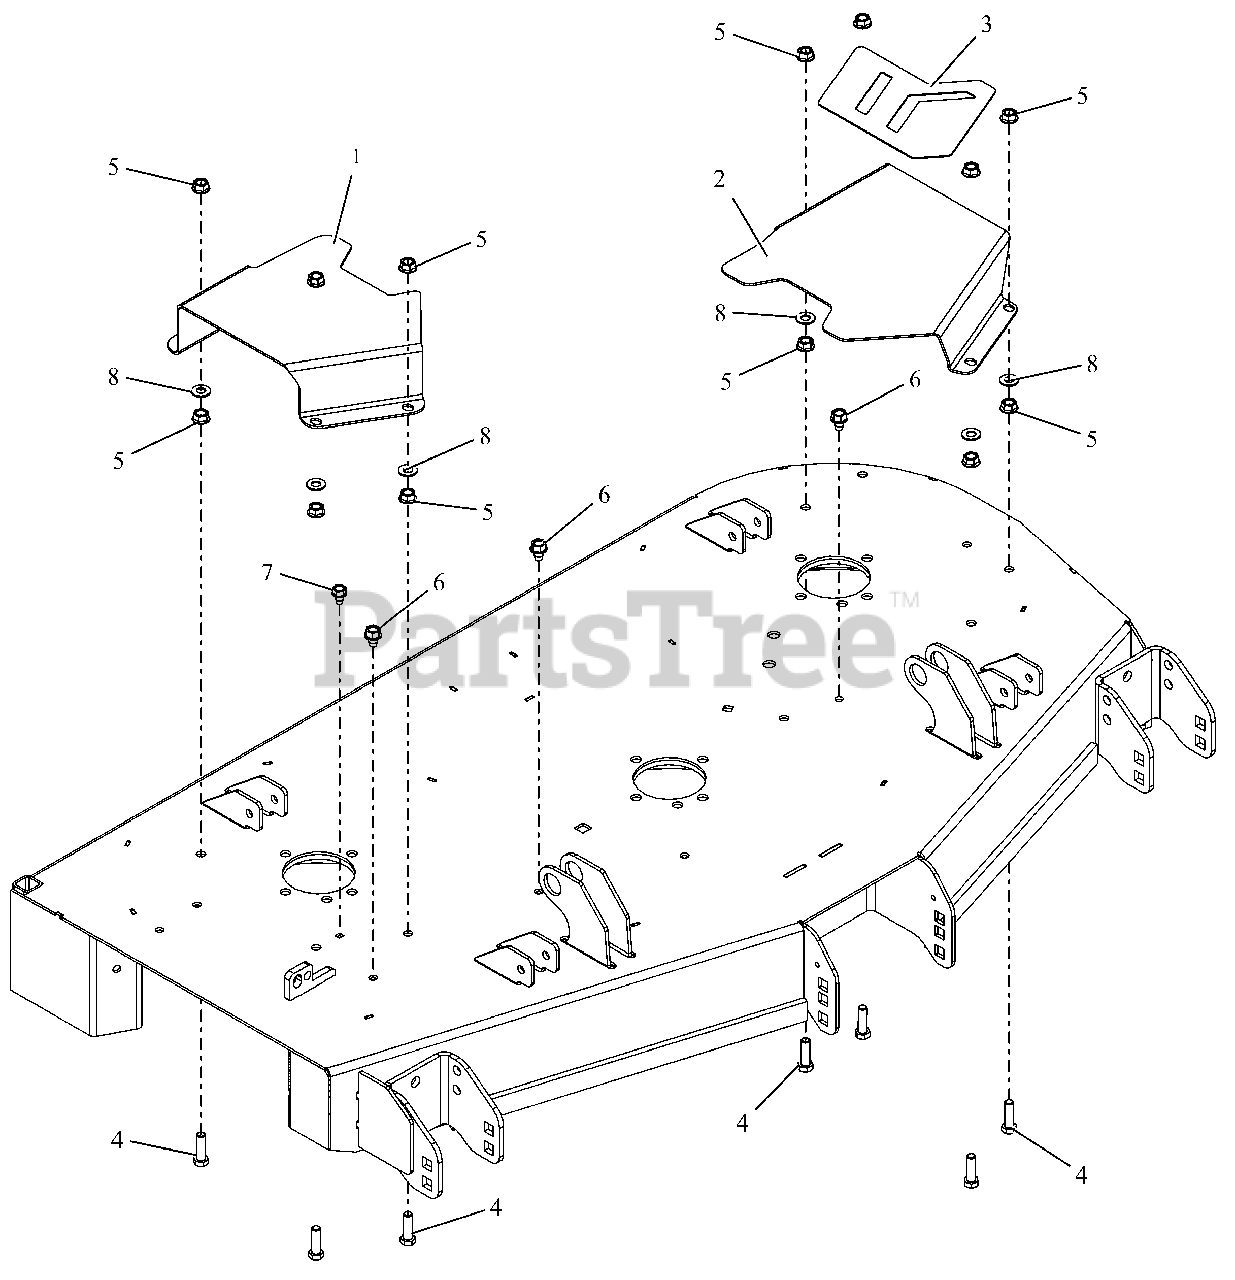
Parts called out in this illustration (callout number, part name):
1	COVER, BELT 48" RIGHT
2	COVER, BELT 48" LEFT
3	GRIP, TAPE 48 BELT COVER
4	@BLT-HEX .38-16X1.25 GR5 YWZC
5	@NUT-SPNLK-FLG .375-16 YWZC
6	@SCR-TAP .38-16X.50 HWH TR YWZ
7	@SCR-TAP .31-18X.50 HWH TR YWZ
8	@WSHR-FL-STL.406X.812X.065 YWZ
